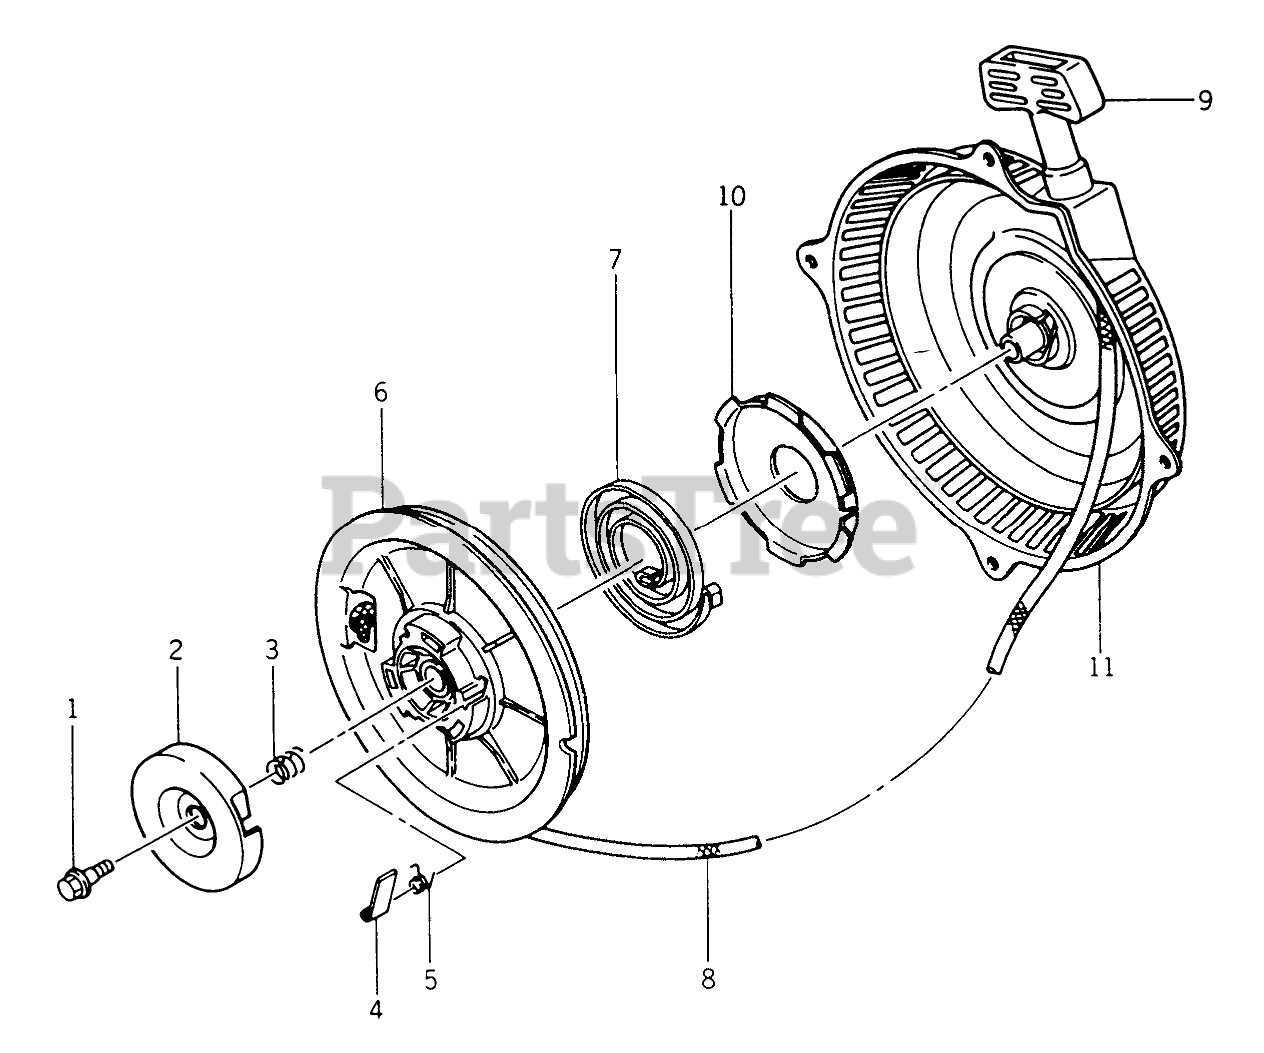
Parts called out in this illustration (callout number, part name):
2	RETAINER-PAWL
3	Return Spring
4	PAWL-RECOIL
5	Return Spring
6	REEL-RECOIL
7	SPRING-RECOIL
8	ROPE-RECOIL 6X1300
9	HANDLE-RECOIL
11	CASE-RECOIL
